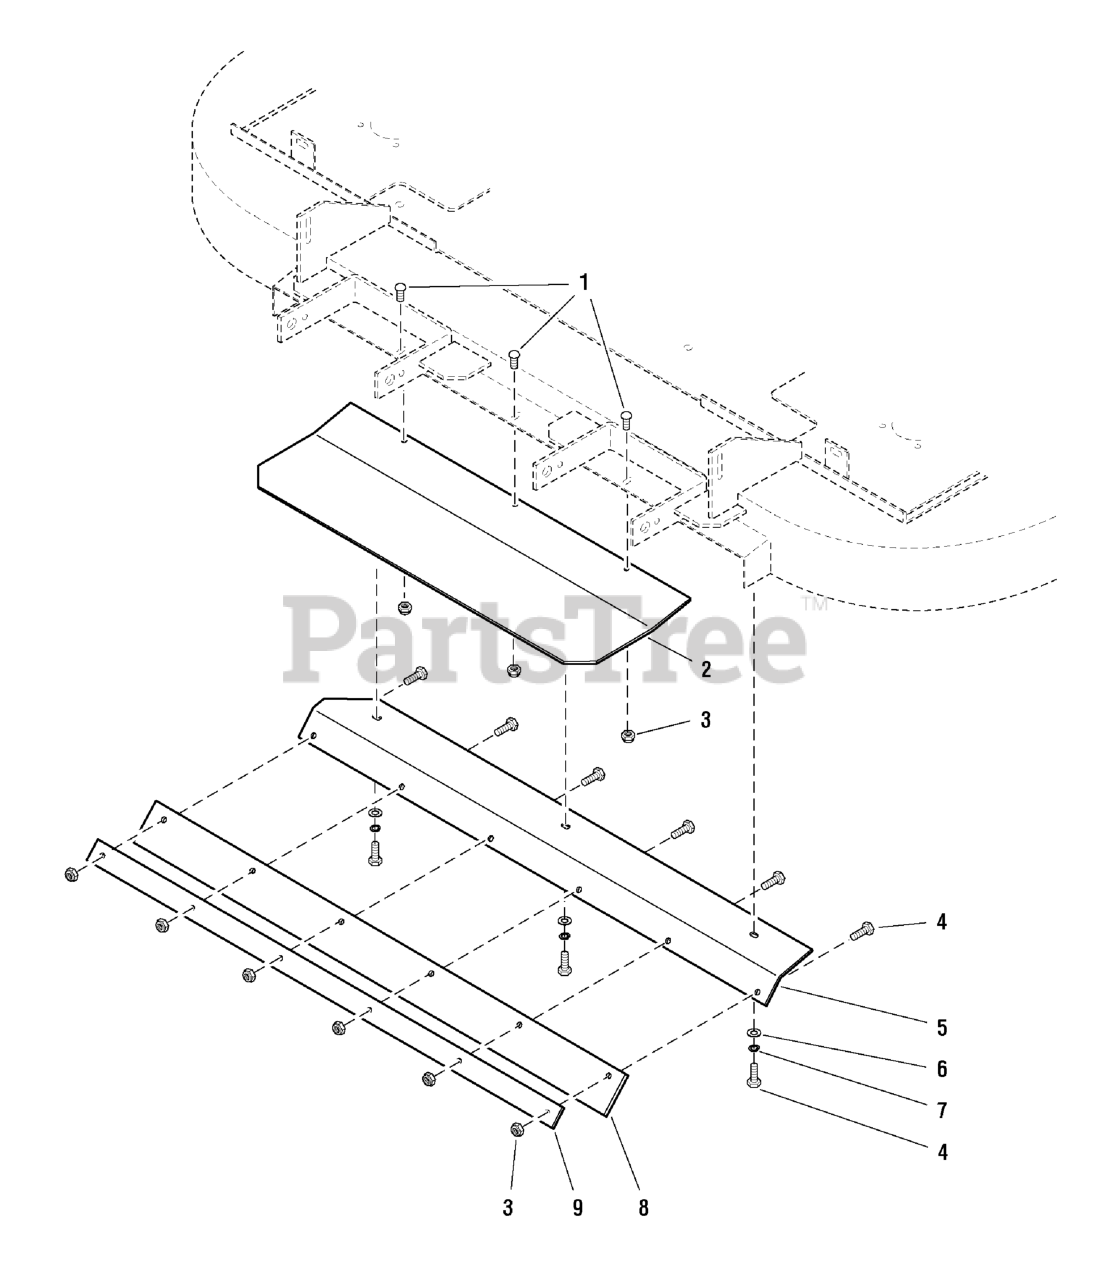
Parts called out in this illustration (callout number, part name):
1	CARRIAGE BOLT, 5/16-18 x 3/4
3	NUT, 5/16-18 Hex Nylon Lock
4	BOLT, 5/16-18 X 1 GD5 YZ
5	DEFLECTOR MOUNT
6	WASHER, 5/16" SAE
7	WASHER, 5/16 LOCK CZ
8	RUBBER DEFLECTOR
9	RETAINING PLATE
